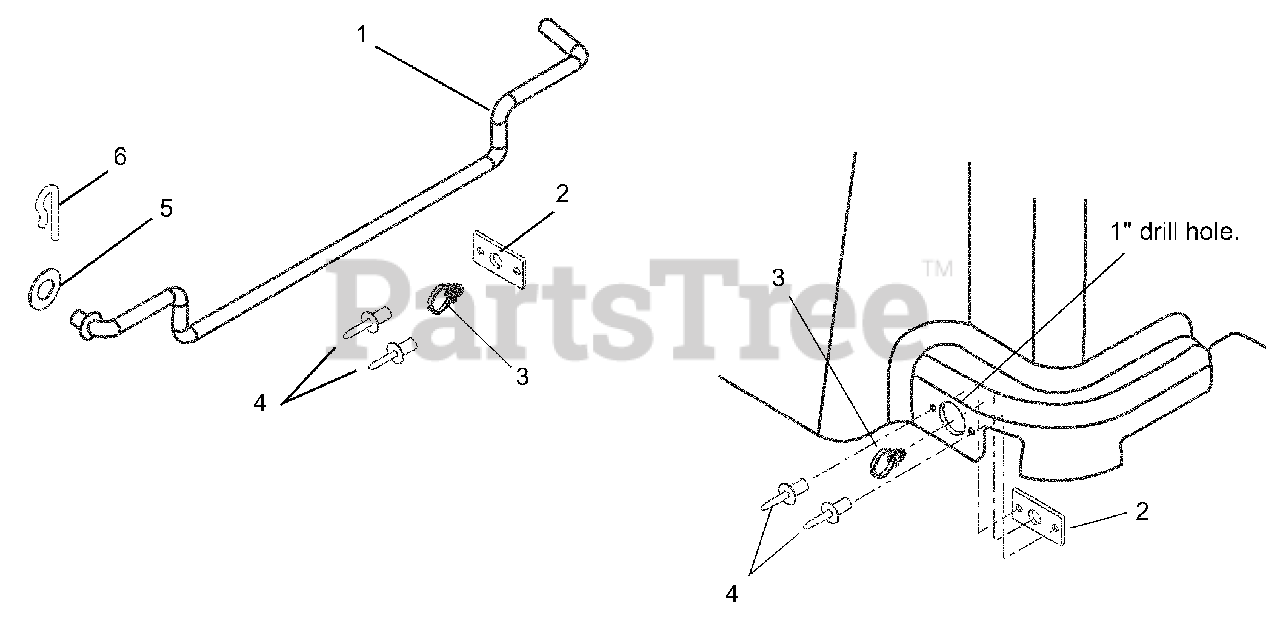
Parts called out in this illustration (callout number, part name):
1	Bagger Prop Rod
2	Rod Clip Plate
3	3/8 Clip
4	3/16 x 7/16 Pop Rivet, Steel
5	13/32 x 13/16 x 1/16 Flat Steel Washer
6	Hair Pin
